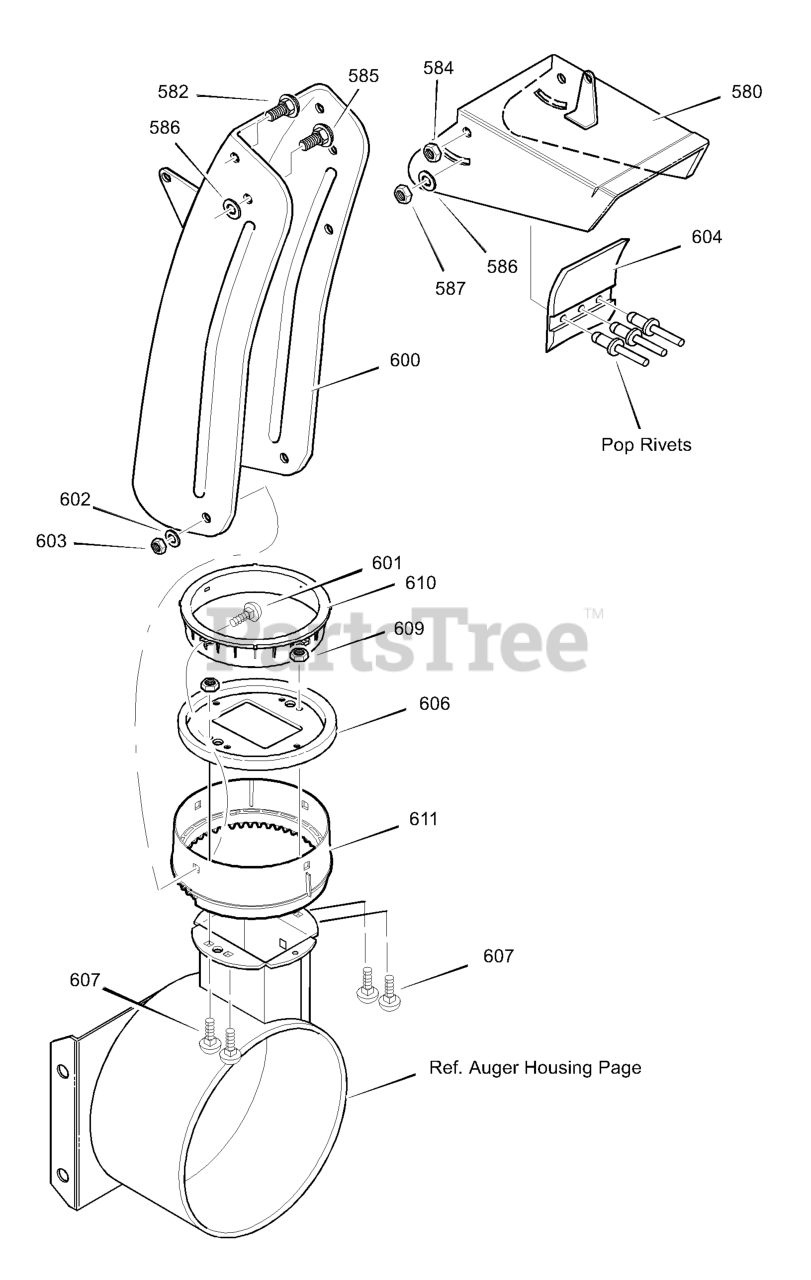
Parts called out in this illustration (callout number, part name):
580	CHUTE, UPPER W/REMOTE
582	SCREW, 5/16-18 x 0.75
584	NUT
585	SCREW, 5/16-18 x 0.75
586	PLASTIC WASHER
587	NUT
600	CHUTE, LOWER W/REMOTE
601	BOLT, 5/16-18 X1.00 CARR
602	WASHER, FLAT
603	NUT
606	CHUTE COLLAR
607	BOLT
609	NUT
610	RETAINER, RING INNER
611	RETAINER, RING OUTER
